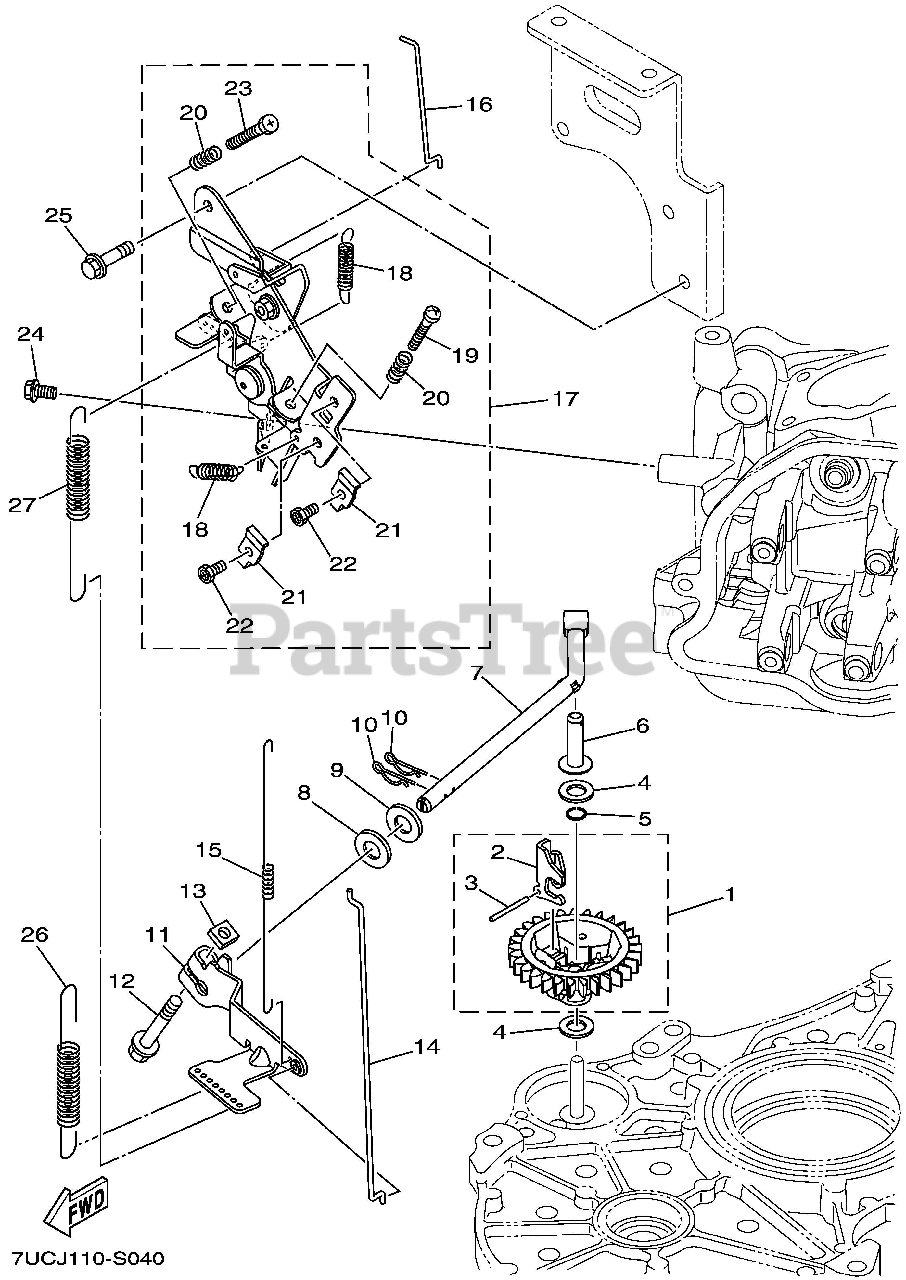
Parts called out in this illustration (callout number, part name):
1	FLYWEIGHT SHAFT ASSY
3	SHAFT, WEIGHT
4	WASHER, PLATE
7	FORK, GOVERNOR
8	WASHER, PLATE
9	WASHER, PLATE
11	GOVERNOR ASSY
12	BOLT, WITH WASHER
13	NUT, SQUARE
14	ROD, LINK
15	SPRING, TENSION
16	ROD, CHOKE 1
17	THROTTLE LEVER COMP.
18	SPRING, TENSION
19	SCREW, THROTTLE
20	SPRING, COMPRESSION
21	PLATE, ADJUST
22	SCREW, HEXAGON
23	SCREW, THROTTLE
24	BOLT, FLANGE
25	BOLT, FLANGE
26	SPRING, GOVERNOR
